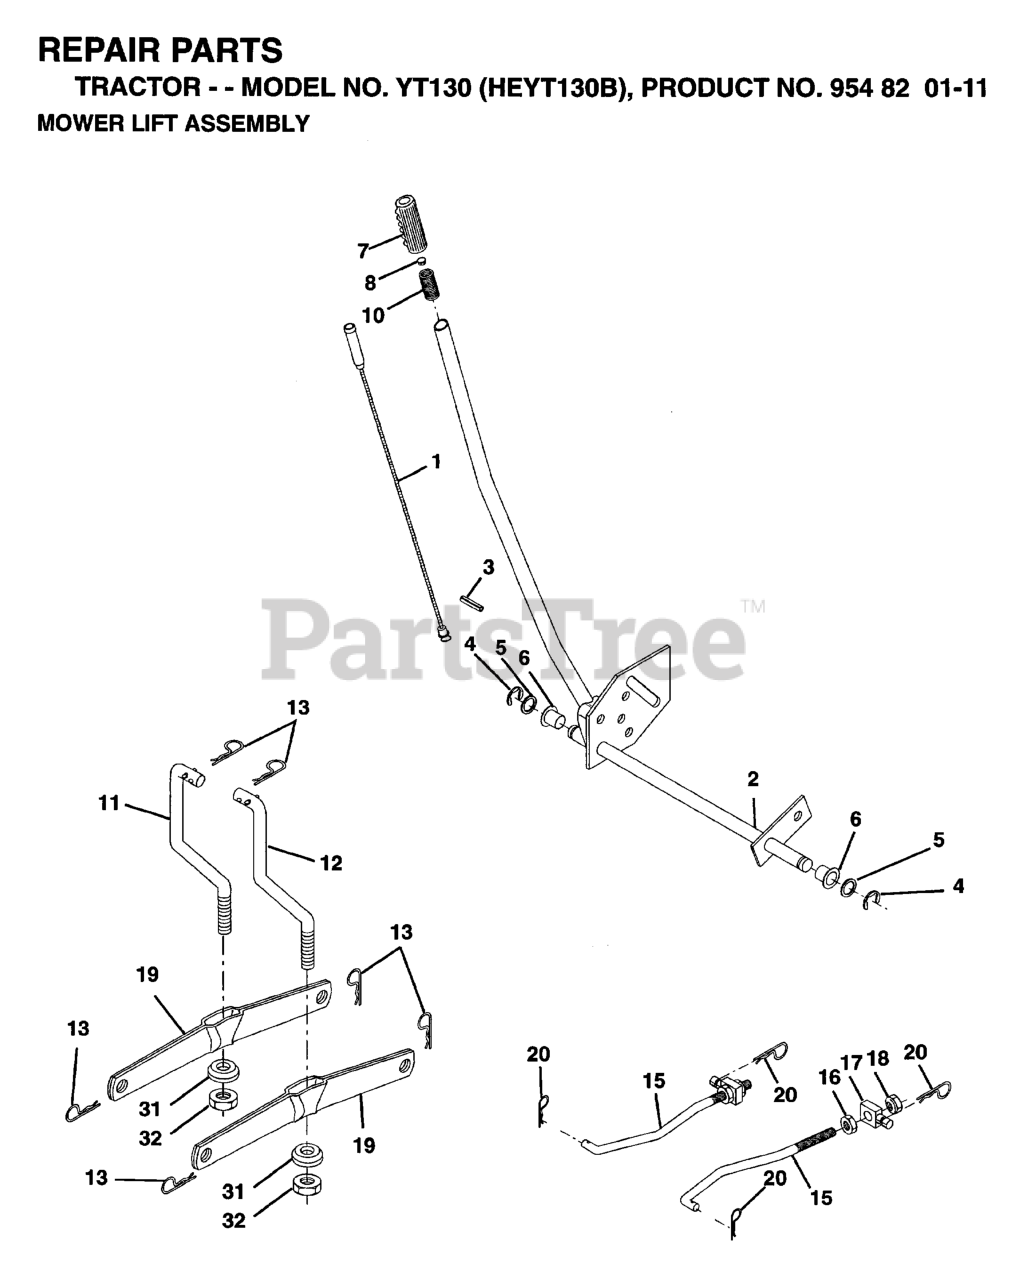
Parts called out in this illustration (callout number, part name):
1	WIRE.INNER.HANDLE.LIFT.LEVER
2	LIFT ARM ASSY
3	PIN GROOVE
4	RETAINING RING LT
6	BEARING.NYLON
7	GRIP HANDLE
8	PLUNGER BUT KIT
10	SPRING, COMP T
11	LINK LIFT LH
12	LINK LIFT RH
13	RETAINER-SPRNG RB
15	FRONT LINK
16	NUT.HEX.JAM.1/2-13
17	TRUNION
18	NUT.LK.W/WSH.1/2.
19	ARM.REAR.SUSPENSION
20	SPRING RETAINER
31	BEARING PIVOT
32	NUT CROWNLOCK 3/8-24
